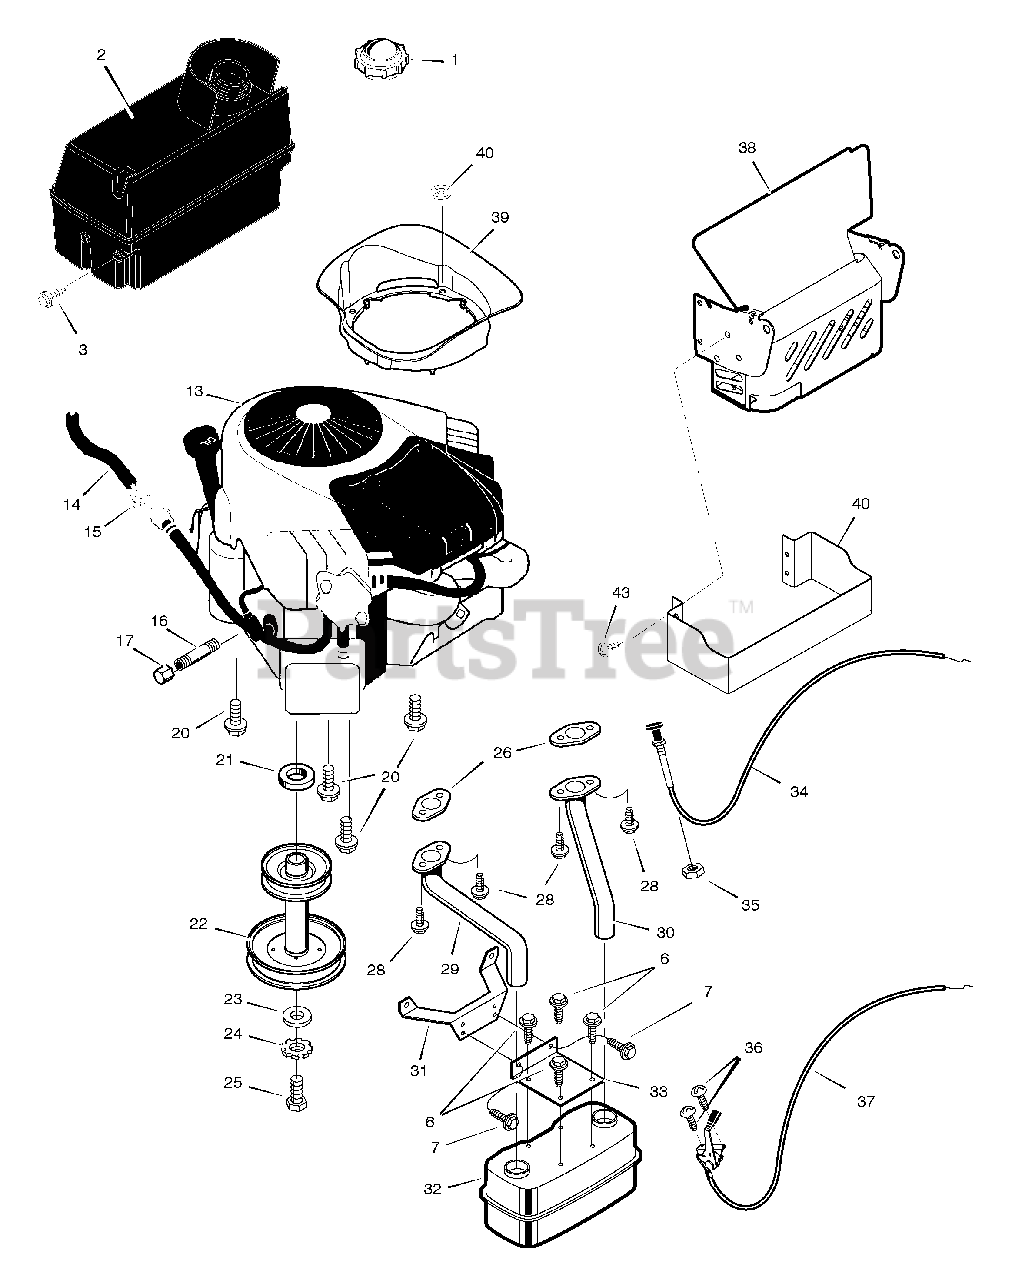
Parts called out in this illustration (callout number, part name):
1	Cap, Fuel
2	Tank, Fuel
13	Engine, Briggs & Stratton *
14	Fuel Line (Must cut to length)
15	Clamp
16	Pipe, Oil Drain
17	Cap, Oil Drain
20	Bolt
22	Pulley, Stack
24	Lockwasher
29	Tube, Right Exhaust
30	Tube, Left Exhaust
31	Bracket, Muffler Mount
32	Muffler
33	Bracket, Muffler
35	Nut
37	Control, Throttle
38	Shield Assembly, Heat
40	GUARD, Heat Shield
41	Speed Nut
